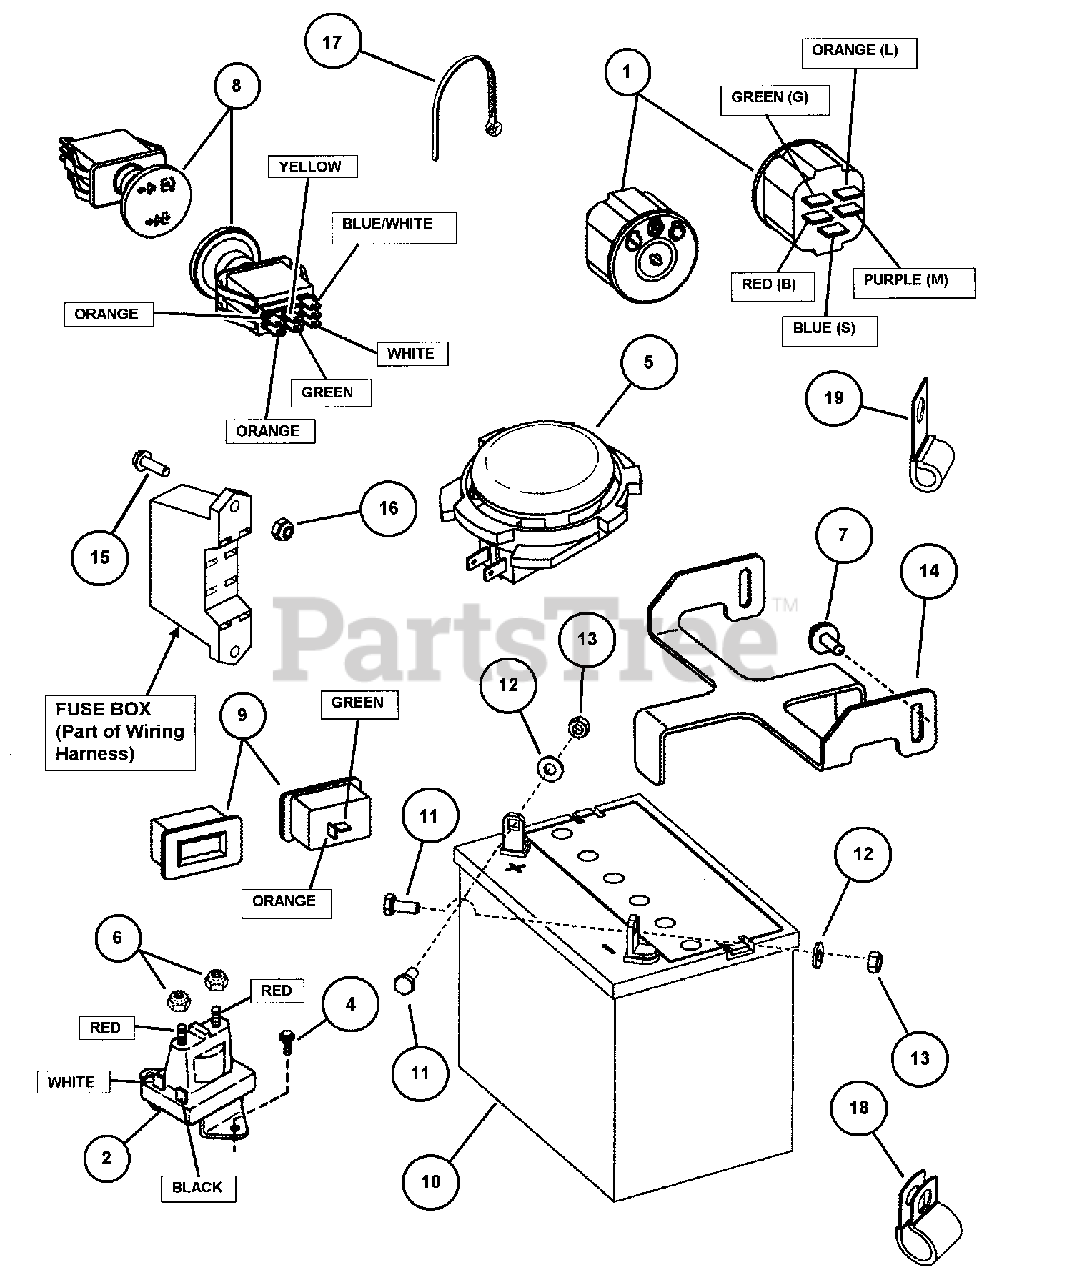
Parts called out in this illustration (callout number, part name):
1	SWITCH, Ignition
2	SOLENOID, Super Trombetta
4	SCREW, 1/4-20 x 1/2" Hex Washer Self-Tap
5	SWITCH, Seat, NC
6	NUT, 1/4-20 HEX NYLON LOCK
7	SCREW, 1/4-20 x 5/8" Hex Head Self-Tap
8	SWITCH, PTO, Yellow
9	HOUR METER w/Flash Alerts
10	BATTERY, 11 Plate 375CCA- Wet
11	SCREW, 1/4-20 x 5/8" Hex Head Cap GR 5
12	WASHER, 1/4" Flat
13	NUT, 1/4-20 Hex Center Lock
14	BRACKET, Battery Hold-Down
15	SCREW, #10-32 x 5/8" Hex Washer Self-Tap
16	NUT, #10-32 Hex Nyloc
18	CLIP, Harness
19	CLIP, Open 3/8" Cushioned
